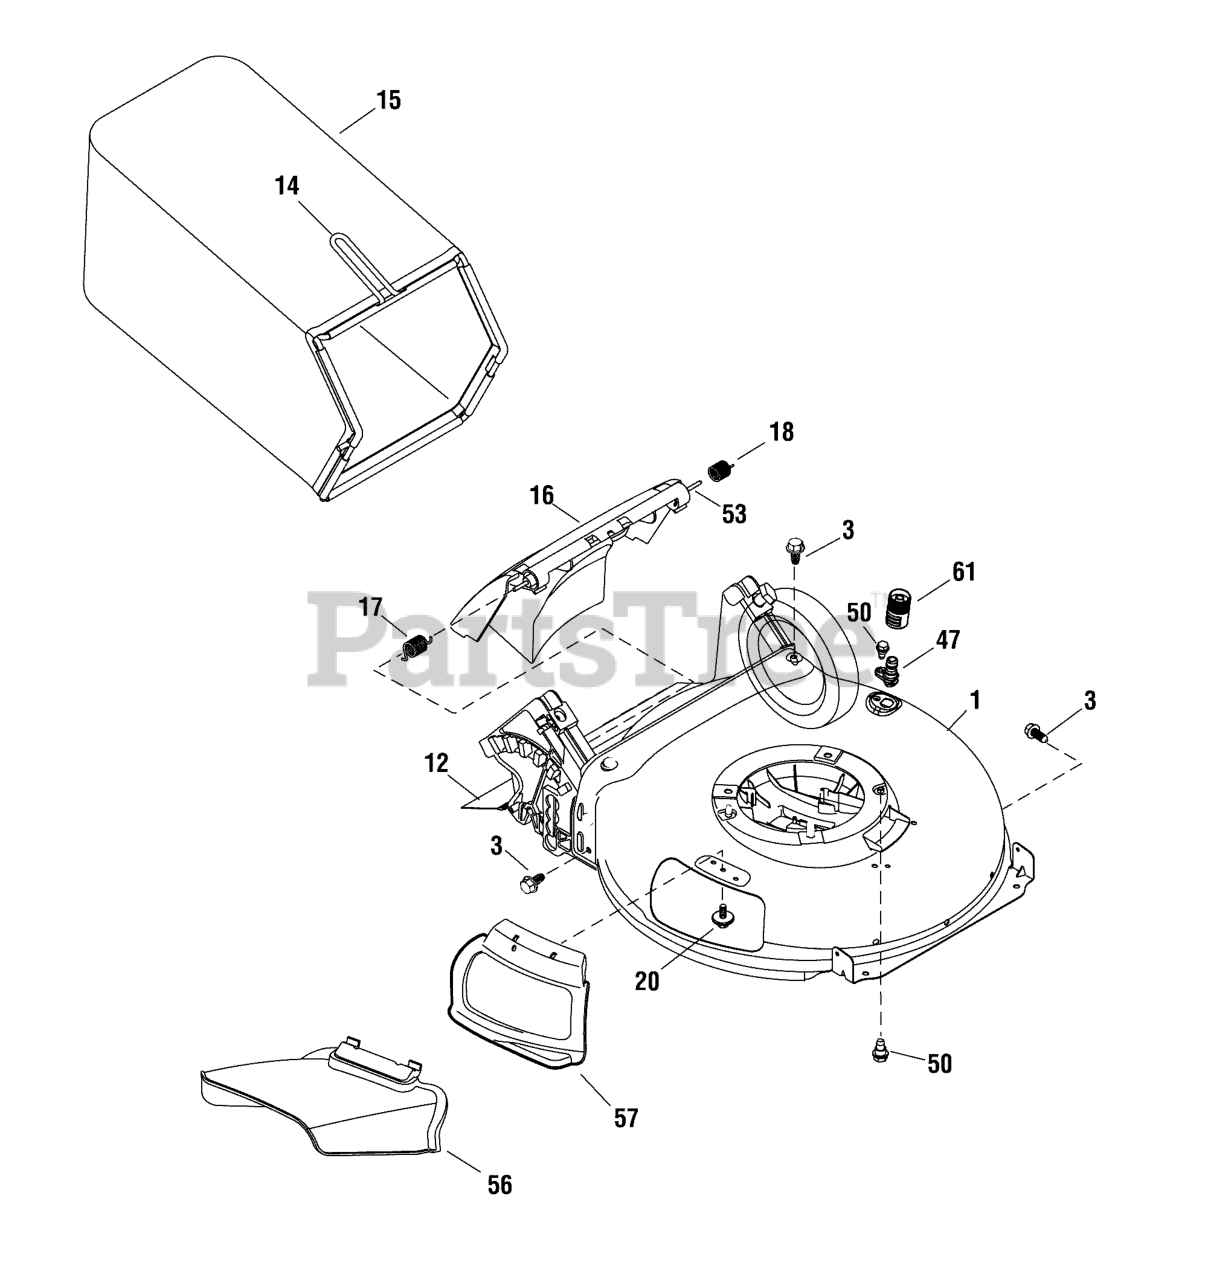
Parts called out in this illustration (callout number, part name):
3	SCREW, 5/16-14 x 3/4
12	SHIELD, Trailing
14	FRAME, Grass Bag
15	BAG, Grass
16	DOOR, Rear Discharge
17	SPRING, Torsion, RH
18	SPRING, Torsion, LH
20	SCREW, Hex Head, 1/4-20 X 1/2
47	NOZZLE, Water
50	BOLT, Shoulder, 1/4-20 x 1/2"
53	ROD, Pivot
56	CHUTE, Side Discharge
57	MULCH PLUG
61	ADAPTER, Water Nozzle
